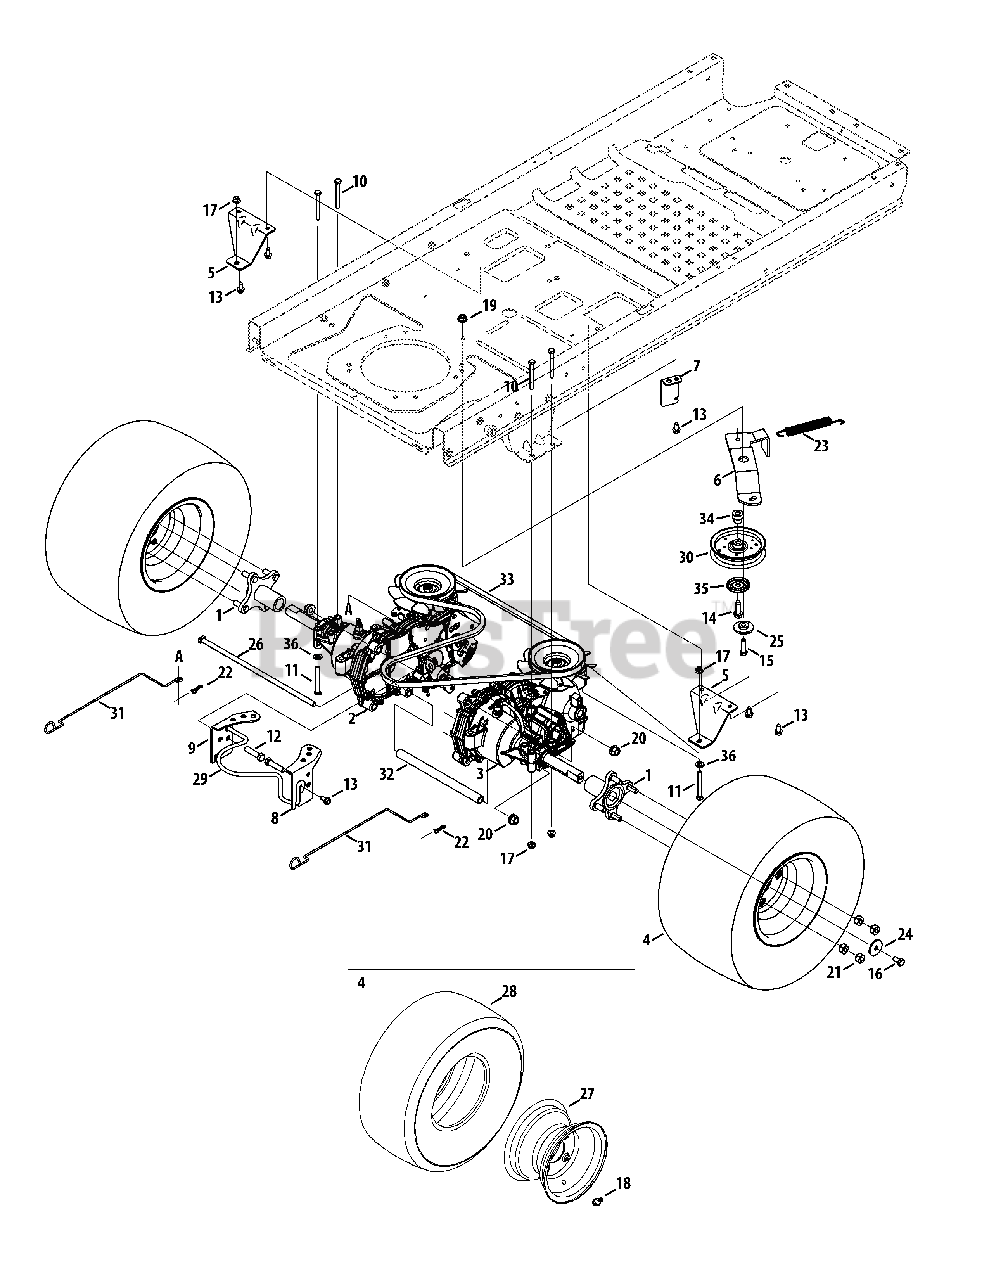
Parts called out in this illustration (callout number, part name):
1	Wheel Hub Assembly
2	Transmission Assembly, LH
3	Transmission Assembly, RH
4	Complete Wheel, 18 x 8.5-8
5	Transmission Mounting Bracket
6	Idler Bracket
7	Spring Mounting Bracket
8	Transmission Bracket
9	Transmission Bracket
10	Hex Screw, 5/16-18 x 2.75
11	Hex Screw, 5/16-18 x 2.25
12	Hex Screw, 7/16-20 x 1.75
13	Hex Washer Screw, 5/16-18 x .750
14	Hex Washer Screw, 3/8-16 x 1.250
15	Hex Screw, 3/8-16 x 1.00
16	Hex Screw, 3/8-16 x .75
17	Flange Lock Nut, 5/16-18
18	Valve Tubeless
19	Jam Lock Nut, 3/8-16
20	Flange Lock Nut, 7/16-20
21	Lug Nut, 7/16-14
22	Bow-Tie Cotter Pin
23	Extension Spring, .75 Dia. x 6.02
24	Flat Washer, .390 x 1.50 x .134
25	Shoulder Spacer, .884 x .190
26	Rod, .405 Dia. x 14.0 LG
28	Tire Only, 18 x 8.5-8
29	Engine Keeper Rod
30	Idler Pulley, 4.25 Dia.
31	Bypass Rod
32	Tube, .51 ID x .75 OD x 10.2
33	Belt, A-Type x 67.0
34	Shoulder Spacer
35	Pulley Cap
36	Flat Washer, .330 x .630 x .064
